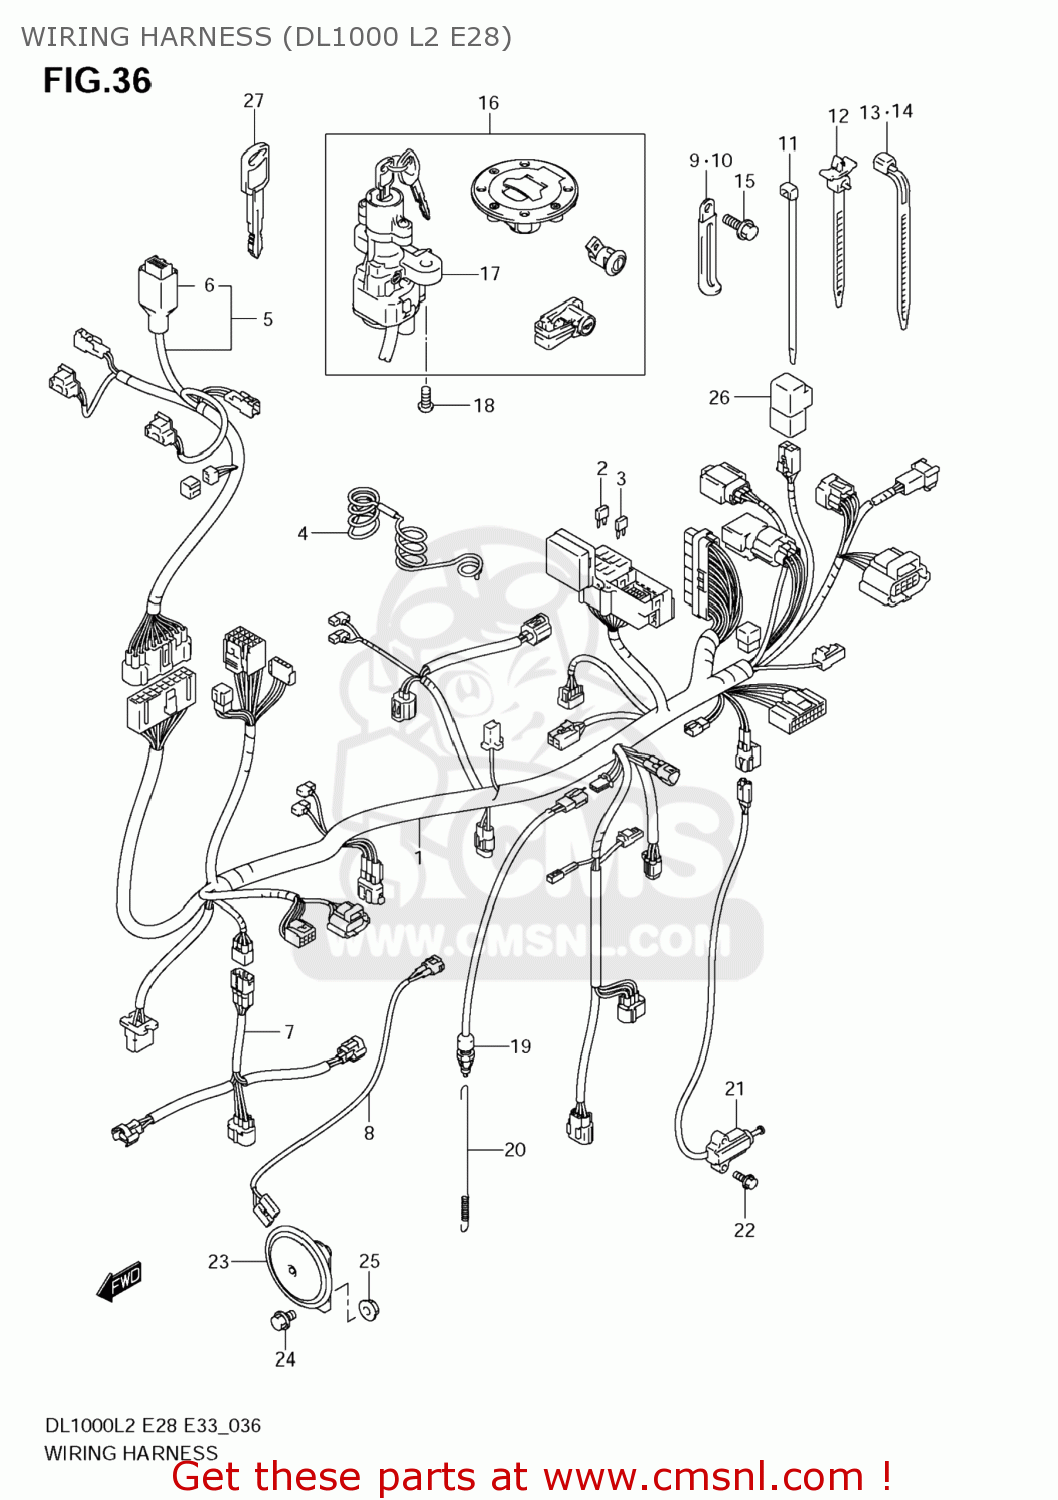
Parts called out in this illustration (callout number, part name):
1	HARNESS,WIRING NO.1
2	FUSE(10A)
3	FUSE(15A)
4	GUIDE,WIRING HARNESS
5	HARNESS,WIRING NO.2
6	COVER,CONNECTOR
7	WIRE,INJECTOR LEAD
8	WIRE,HORN LEAD
9	CLAMP(L:45)
10	CLAMP(L:80)
11	CLAMP(L:145)
12	CLAMP
13	CLAMP(L:95)
14	CLAMP(L:125)
15	BOLT
16	LOCK SET
17	LOCK ASSY,STEERING
18	BOLT(8X20)
19	SWITCH ASSY,STOP LAMP
20	SPRING,STOP LAMP SWITCH
21	SWITCH ASSY,SIDE STAND
22	BOLT
23	HORN ASSY
24	BOLT
25	NUT
26	RELAY ASSY
27	KEY,BLANK
